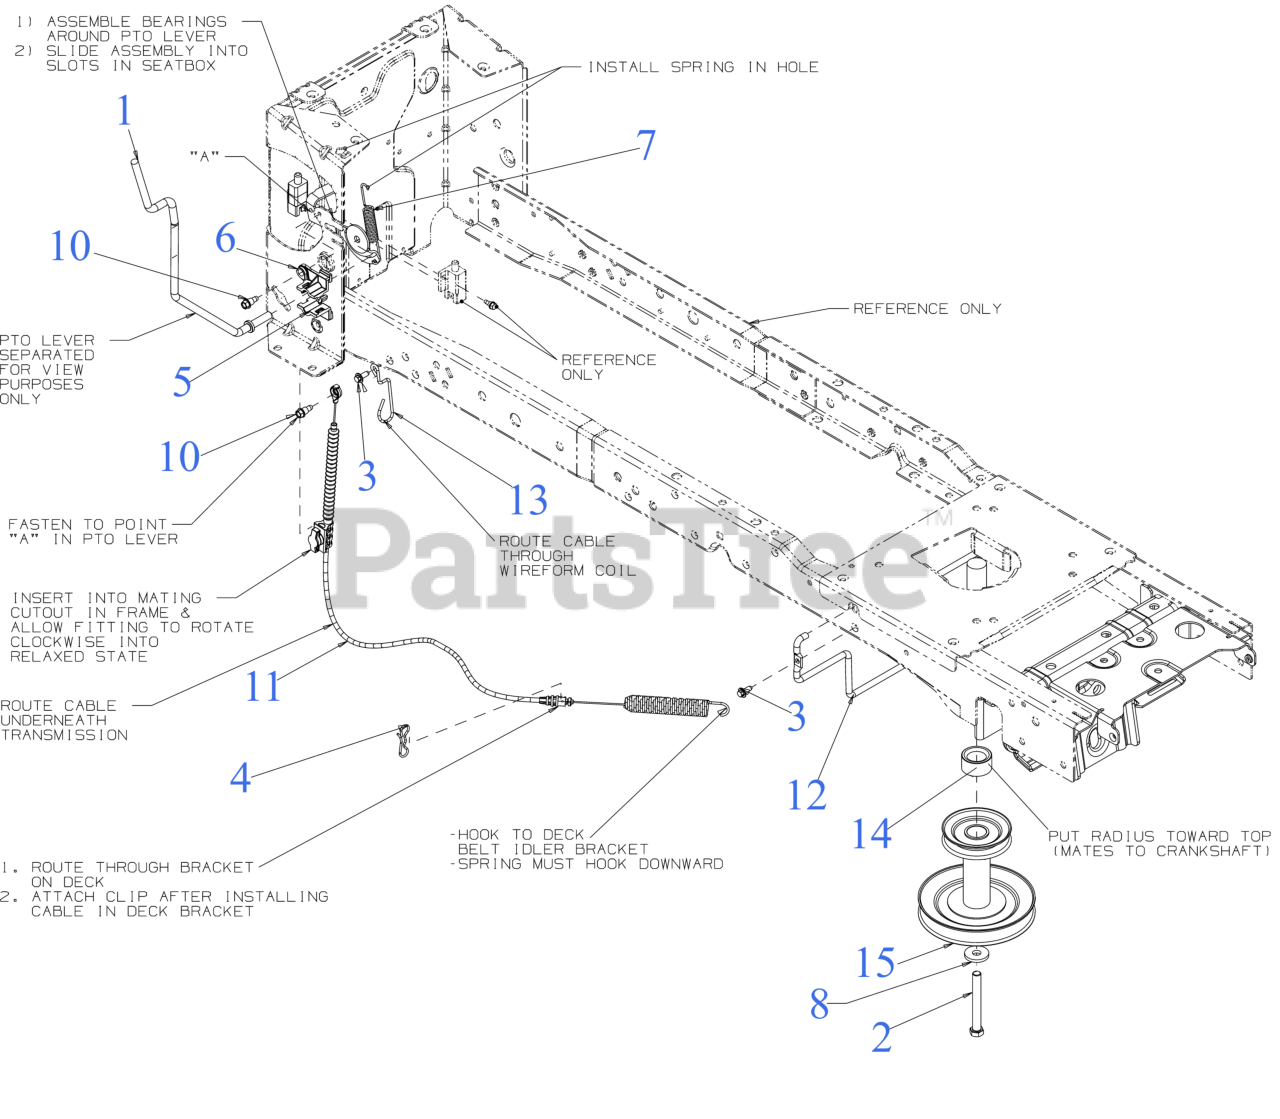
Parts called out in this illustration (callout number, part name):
1	PTO HANDLE ASSEMBLY
2	SCREW 7/16-20 x 3.5 GR5
3	SCREW M6-1 x .625
4	BOW TIE COTTER PIN
5	PTO HANDLE BOTTOM BEARING
6	PTO HANDLE TOP BEARING
7	EXTENSION SPRING .56 OD x 4.52
8	FLAT WASHER .445 x 1.248 x .170
10	SHOULDER SCREW
11	PTO HANDLE CABLE
12	BELT KEEPER ROD
13	CABLE GUIDE WIRE
14	ENGINE PULLEY SPACER
15	ENGINE PULLEY (3.56 x 6.12 DIA)
